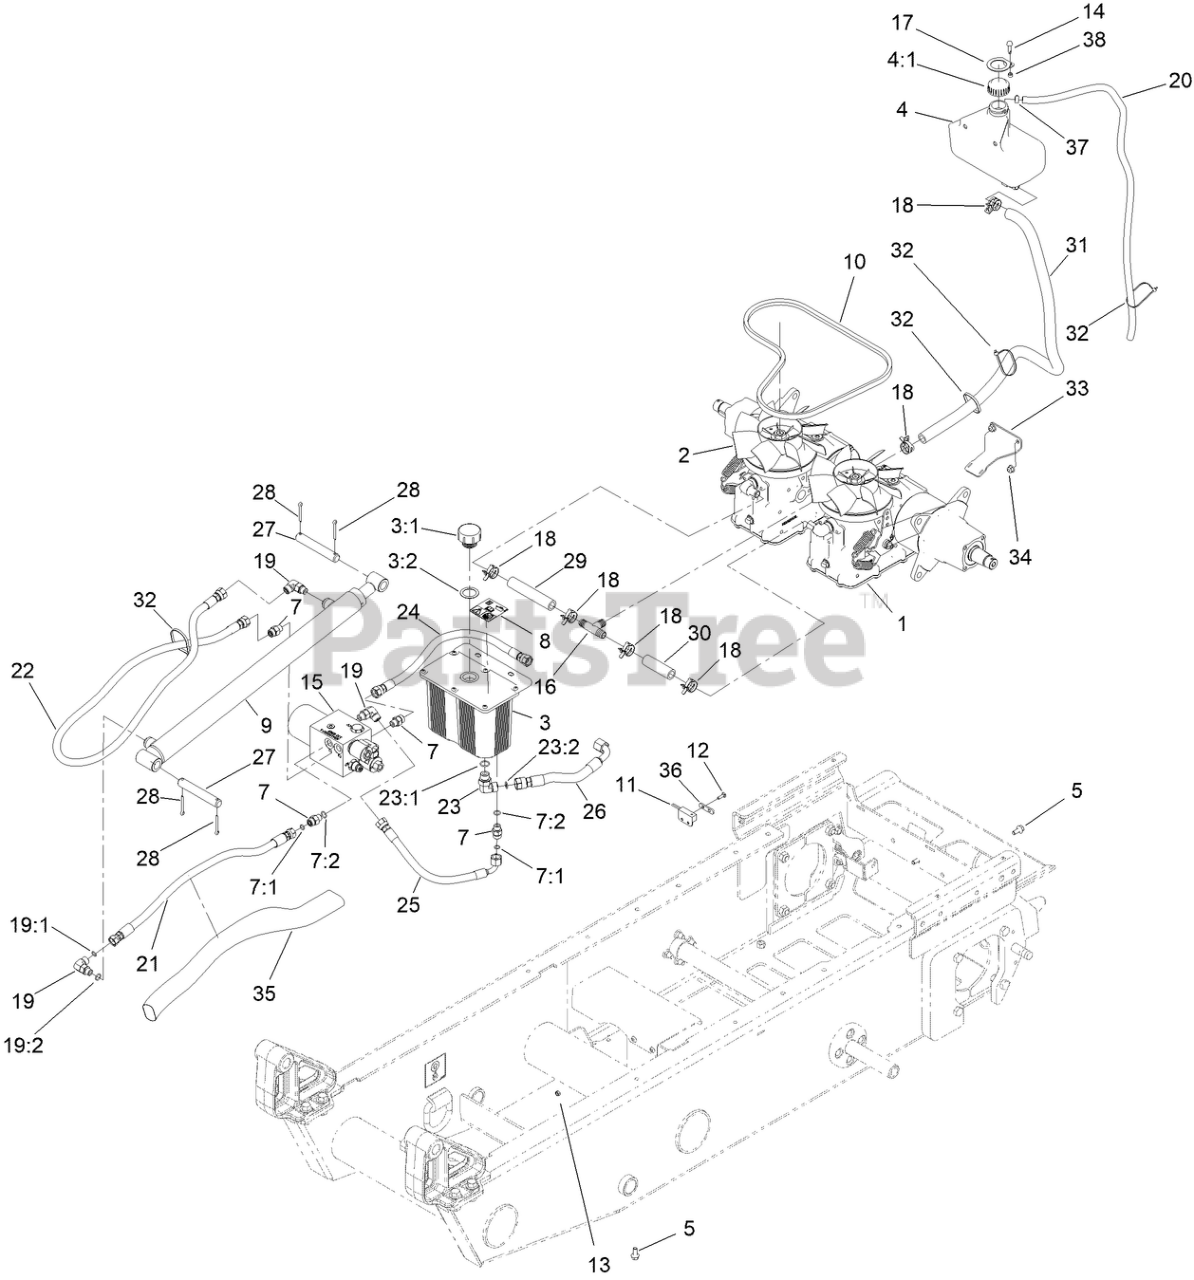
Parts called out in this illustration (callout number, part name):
1	LH HYDRO TRANSAXLE ASM
2	RH HYDRO TRANSAXLE ASM
3:1	CAP-RESERVOIR, HYD
3:2	GASKET-CAP
4	TANK-HYDRAULIC
4:1	CAP-VENTED
5	SCREW-HHF
7	FITTING-STRAIGHT
7:1	O-RING
7:2	O-RING
8	DECAL-WARNING
9	CYLINDER-HYDRAULIC
10	BELT AND SPRING KIT
11	SWITCH-PROXIMITY
12	SCREW-CARR
13	NUT-LOCK, NI
15	HYDRAULIC MANIFOLD ASM
17	LOCK-TANK
18	CLAMP-SC BAND
19	FITTING-ELBOW, 90 DEG
19:1	O-RING
19:2	O-RING
20	HOSE-BREATHER, TRANSMISSION
21	HOSE-HYDRAULIC
22	HOSE ASM-HYD
23	FITTING-ELBOW, 90 DEG
23:1	O-RING
23:2	O-RING
24	HOSE ASM-HYD
25	HOSE ASM-HYD
26	HOSE ASM-HYD
27	PIN-PIVOT
28	PIN-COTTER
29	HOSE-HYD, HYDRO
30	HOSE-HYD, HYDRO
31	HOSE-HYD, HYDRO
32	TIE-CABLE
33	BRACKET-HOSE RETAINER
34	NUT-HF, NI
35	SLEEVE-PROTECTIVE
36	PLATE-SWITCH, PROXIMITY
37	CLAMP-HOSE
38	SPACER
